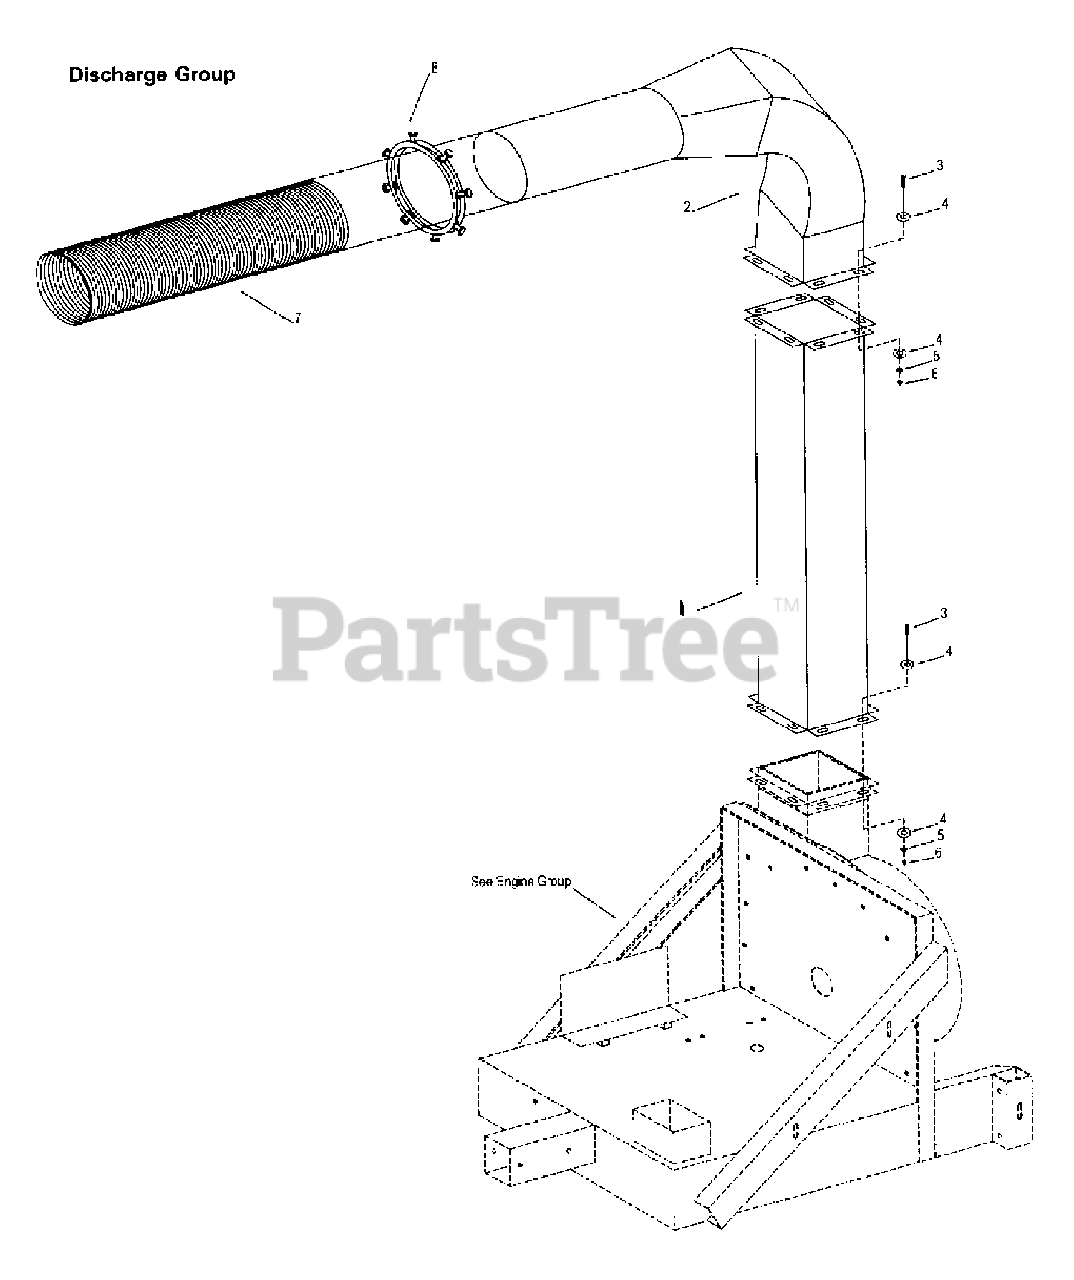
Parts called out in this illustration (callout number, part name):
1	Discharge Stack
2	Discharge Elbow
3	3/8-16 x 1-1/4" Hex Bolt
4	3/8 Flat Washer
5	3/8 Lock Washer
6	3/8-16 Hex Nut
7	Hose, Discharge 8" x 5' Metal
8	Ring, Squeeze 8"
